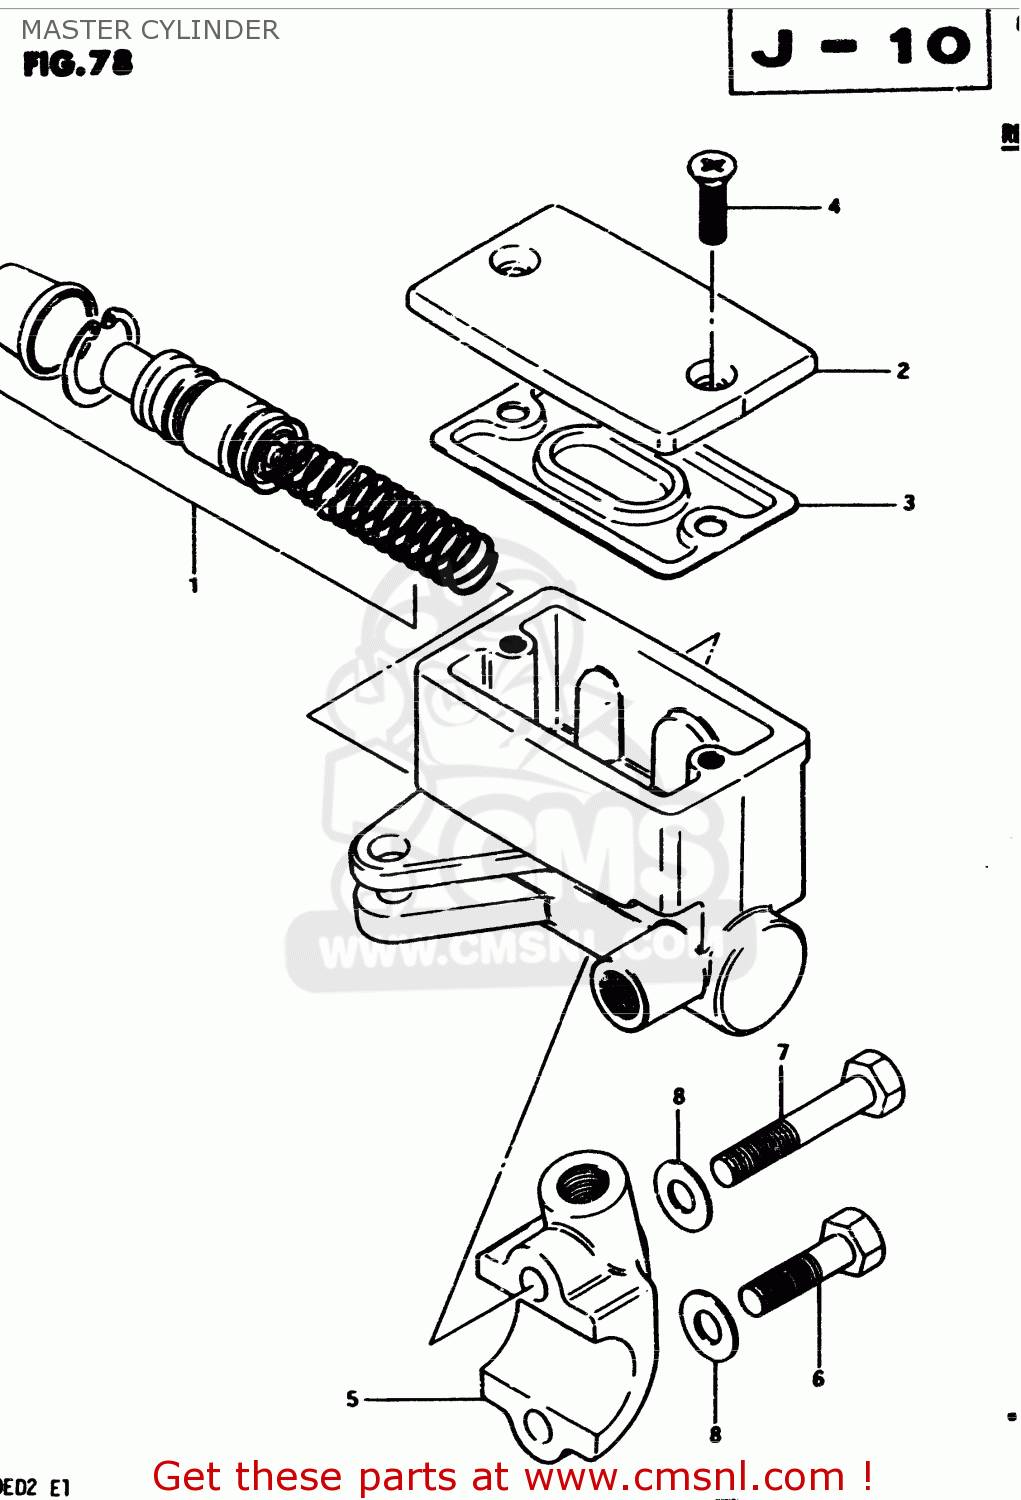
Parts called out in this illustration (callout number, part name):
1	PISTON & CUP SET
2	CAP
3	4
4	SCREW
5	HOLDER
6	BOLT
7	BOLT 6X40
8	WASHER
